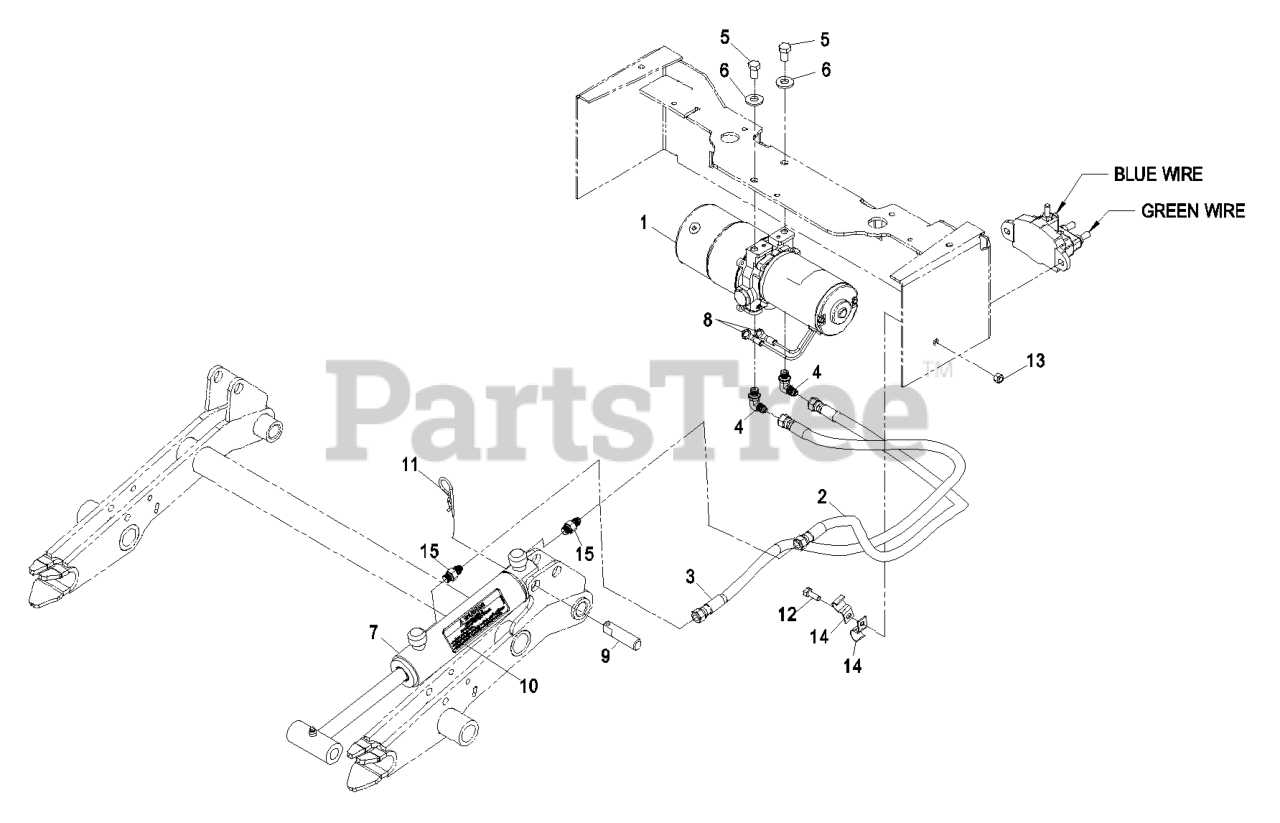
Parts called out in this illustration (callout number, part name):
2	ASM,HYDRAULIC HOSE -4
3	ASM,HYDRAULIC HOSE -4
4	ADAPTER,90 DEG
5	SCREW-HH
6	WASHER-BELLEVILLE
7	ASM,FMZ HYD CYLINDER
8	TERMINAL,RING 5/16" INSUL
9	PIN,CYLINDER MOUNT RR
10	DECAL,HIGH PRESSURE OIL
11	PIN-COTTER
12	SCREW-HH
13	NUT-LOCK, NI
14	CLIP-HALF, LOOM
15	ADAPTER,STRAIGHT ORIFICED
